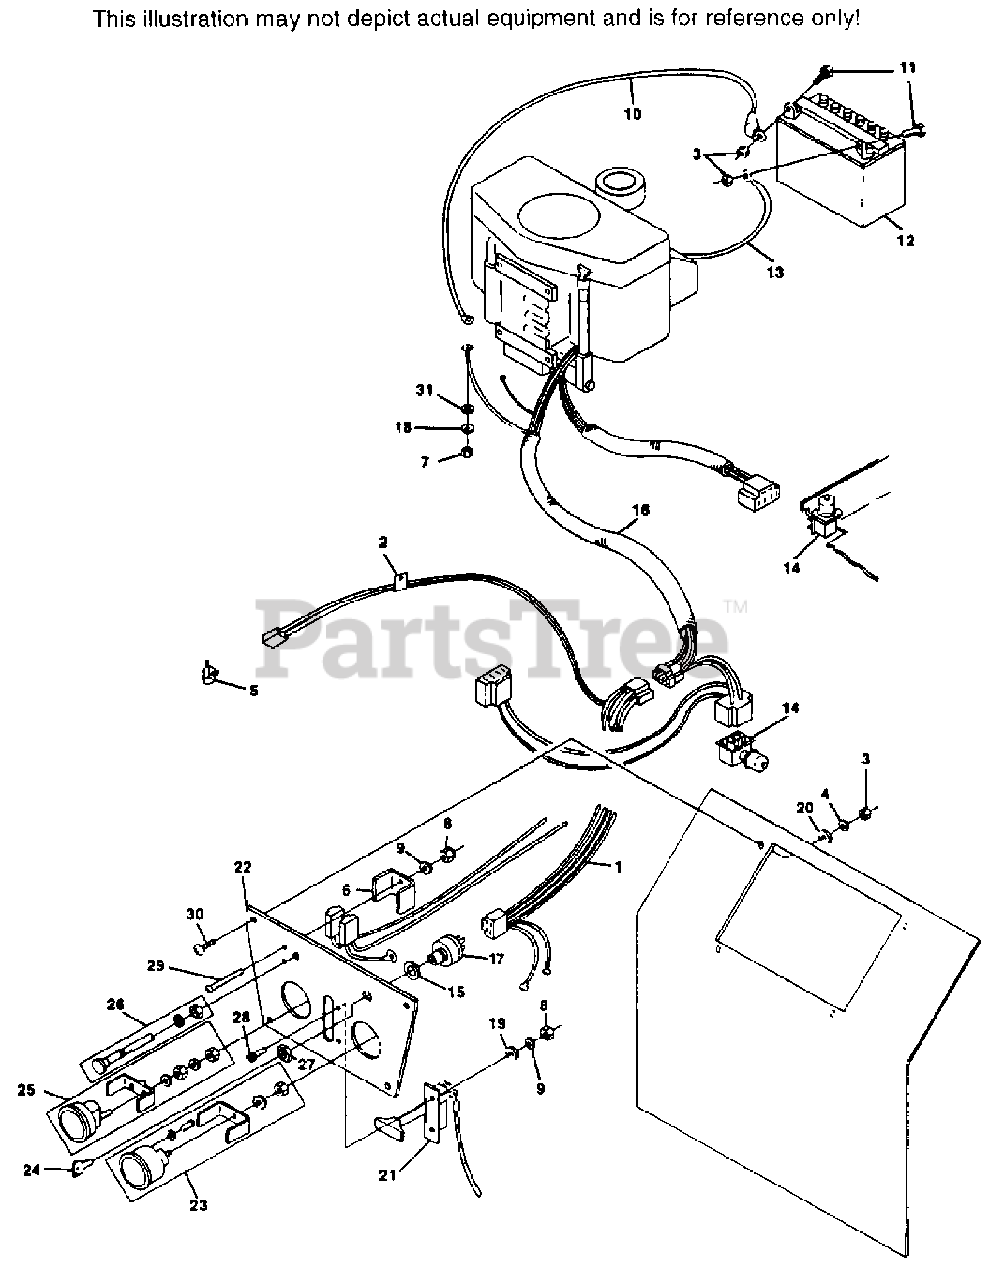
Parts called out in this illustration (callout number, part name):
1	WIRE HARNESS, INSTRUMENT PANEL
5	SWITCH, SEAT
6	BRACKET, FUSE HOLDER
7	HEX NUT, MS-METRIC
9	LOCKWASHER, #10 EXTERNAL TOOTH
10	BATTERY CABLE - 30-3/4"(RED)
12	BATTERY
13	BATTERY CABLE - 13-3/4"(BLACK)
14	SWITCH, CUTTER DECK ENGAGE
15	LOCK WASHER, 5/8" INTERNAL TOOTH
16	WIRE HARNESS - LOWER
17	SWITCH, IGNITION
21	THROTTLE CONTROL
22	INSTRUMENT PANEL
23	HOURMETER(INCLUDES HARDWARE)
24	IGNITION KEY
25	AMMETER(INCLUDES HARDWARE)
26	CHOKE CONTROL
27	HEX NUT, 5/8-11
